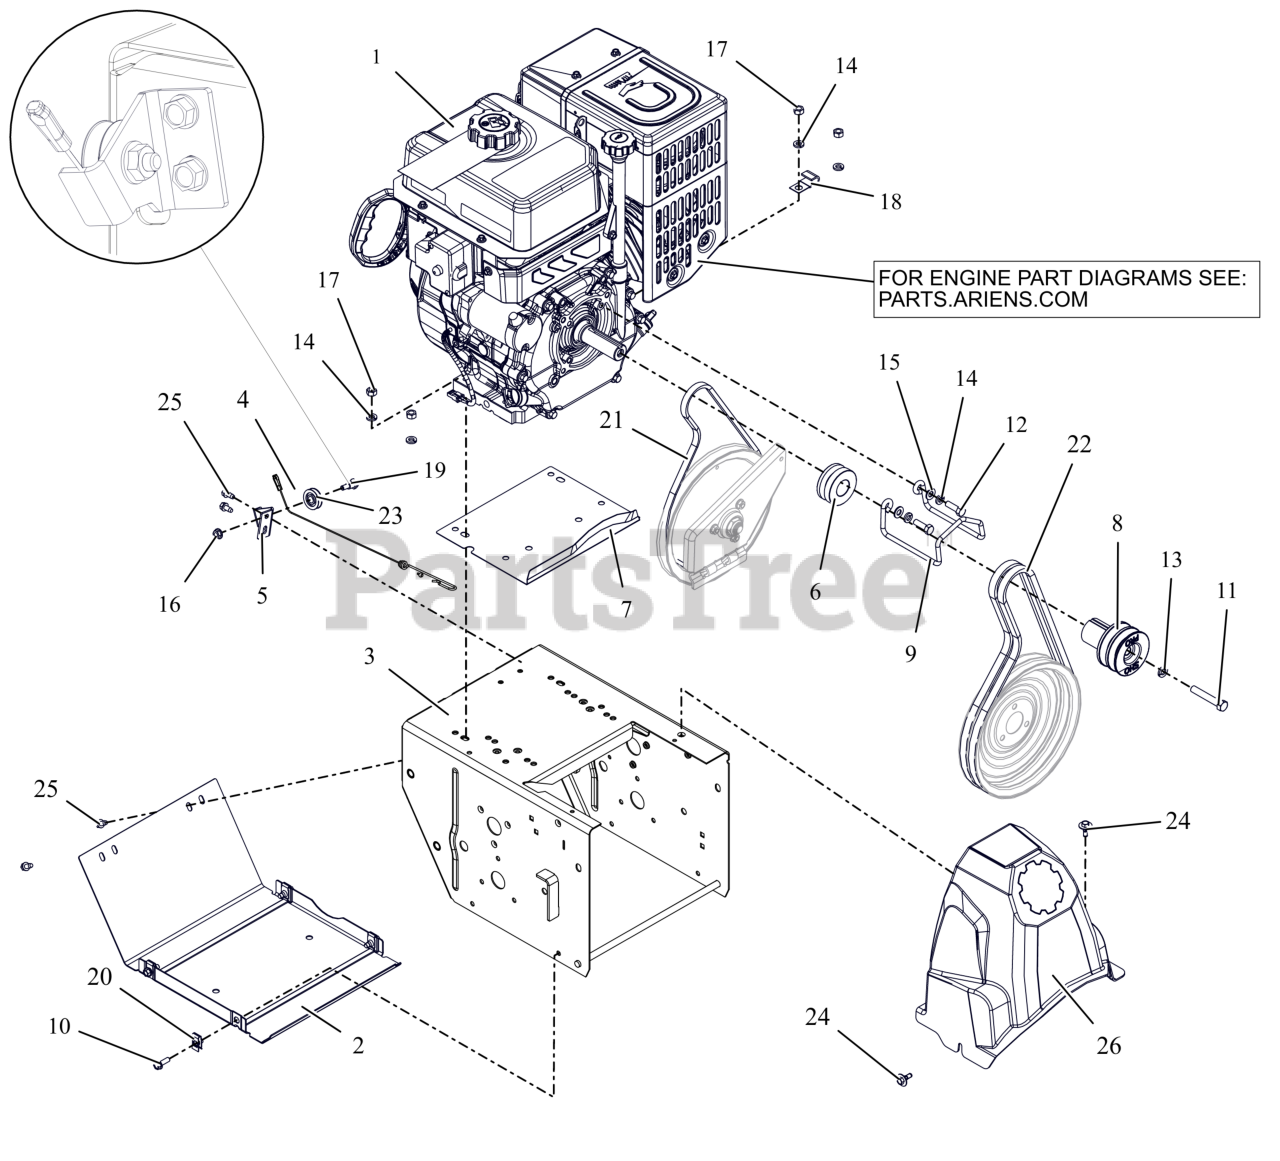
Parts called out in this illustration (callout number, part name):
1	ENGINE, ARIENS AX301 240V/60W
2	COVER, BOTTOM
3	FRAME, MAIN - 14GA DELUXE (ORANGE)
4	CABLE, LOWER TRACTION,SS & PRO
5	BRKT, CABLE PULLEY
6	SHEAVE, TRACTION (KEYLESS)
7	BAFFLE, WATER - LARGE BLOCK (ORANGE)
8	SHEAVE,ATTACHMENT-SHO 2 GRV
9	FINGER, BELT
10	BLT, HWH .25-20X.75 G5 ZCC
11	BLT, HEX .38-24X2.25 G5 ZCC
12	BLT, HEX 0.3125-24X1 G5 ZCC
13	WSHR,LK-REG .375X.094 ZCC
14	WSHR, LK-HVY .312X.097 ZCC
15	WSHR,FLT .344X.688X.065 ZCC
16	NUT-LK-TOP-FLG .250-20 GF ZCC
17	NUT, HEX .312-18 ZCC
18	J-CLAMP
19	BOLT, SHLDR -.375 X .375 X .25-20
20	NUT-RTNR .25-20X.56
21	V-BELT, 3L-WRAPPED
22	V-BELT, HA-RAW EDGE (SET)
23	PULLEY, CABLE
24	SCR-TAP .25-20X.5 CAPTIVE
25	SCR-TAP .25-20X.50 HWH ZCC
26	COVER, BELT
